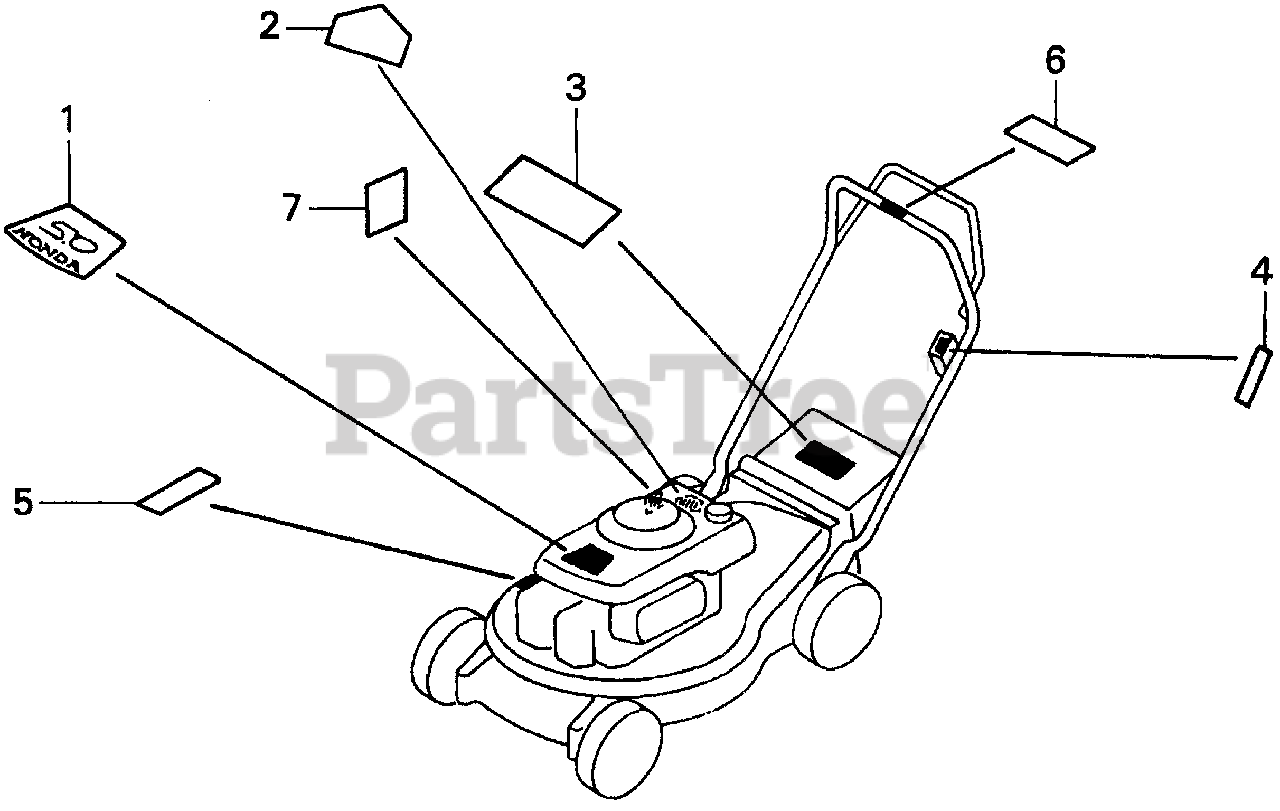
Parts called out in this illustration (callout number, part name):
1	MARK, EMBLEM
2	LABEL C, HOUSING CAUTION
3	LABEL, WARNING (ENGLISH)
4	MARK, THROTTLE (ENGLISH)
5	LABEL, HEAT WARNING
6	MARK, BLADE CONTROL (ENGLISH)
7	MARK, OIL CAUTION
